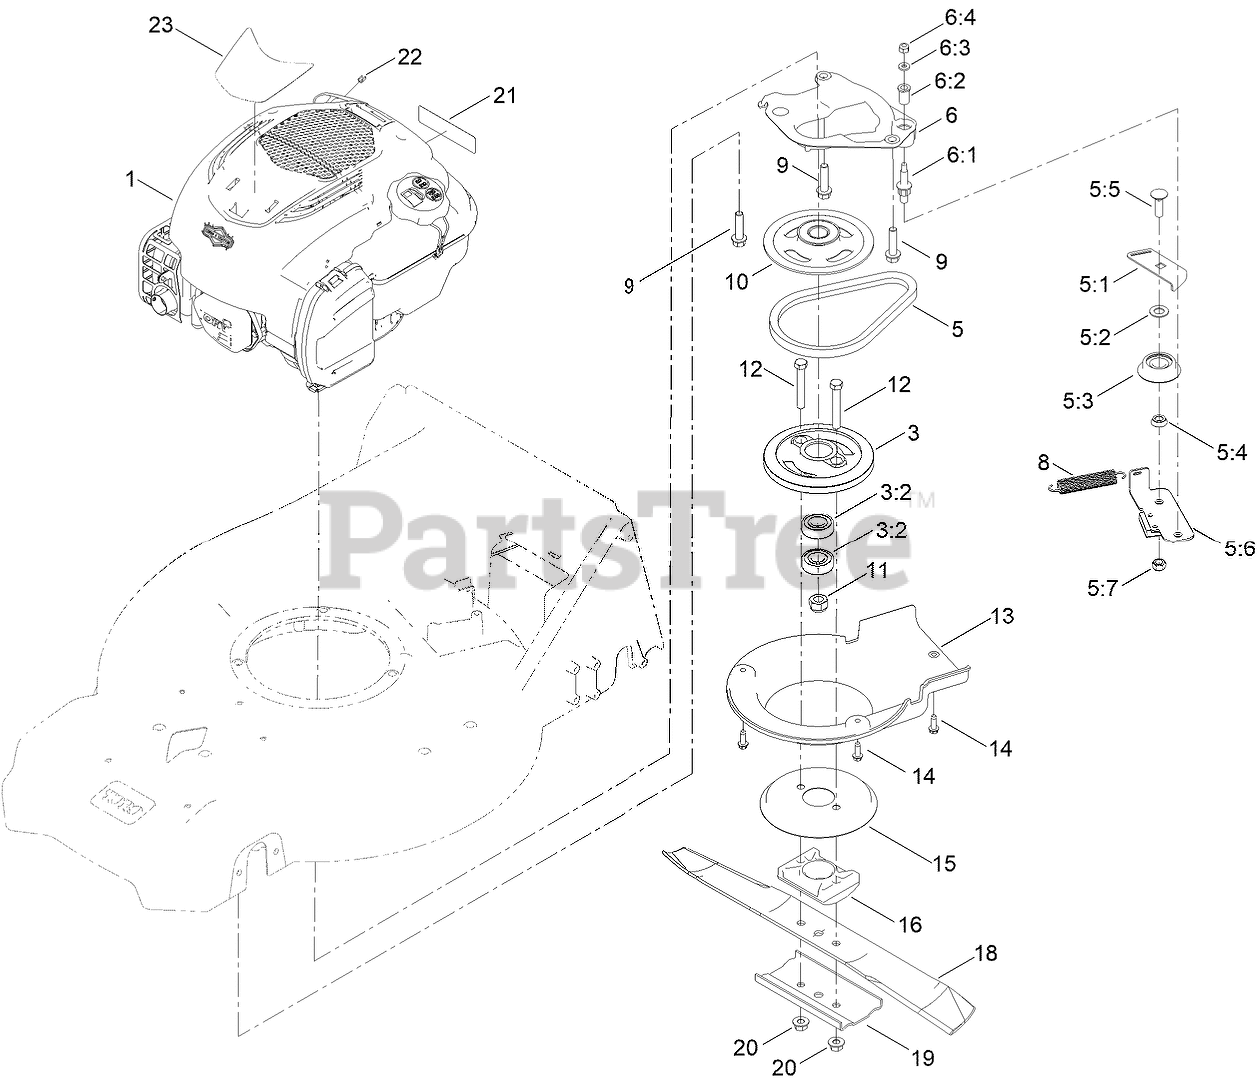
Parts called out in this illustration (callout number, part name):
1	ENGINE-BRIGGS 725 EXI BBC
3	DRUM-BBC
3:2	BEARING-BALL
5	BRAKE-BBC
5:1	BELT
5:2	PLATE-GUIDE
5:3	SPACER
5:4	RETAINER-BBC
5:5	SPACER-BEARING
5:6	BOLT-CARR
5:7	PLATE-BRAKE
6	PLATE-ANCHOR,BBC
6:1	PLATE-ANCHOR
6:2	BOLT-SHOULDER
6:3	BUSHING
6:4	WASHER-FLAT
8	SPRING-TENSION, BRAKE
9	SCREW-HWH
10	PULLEY
11	NUT-HEX
12	SCREW-HH
14	SCREW-HWHTF
16	SUPPORT-BLADE
18	BLADE-21IN, RECYCLING
19	SUPPORT-BLADE
20	NUT-FLANGE, LOCK
21	DECAL-ARRESTOR, SPARK
22	STOP-ROPE
23	DECAL-BRIGGS, 163CC BBC
